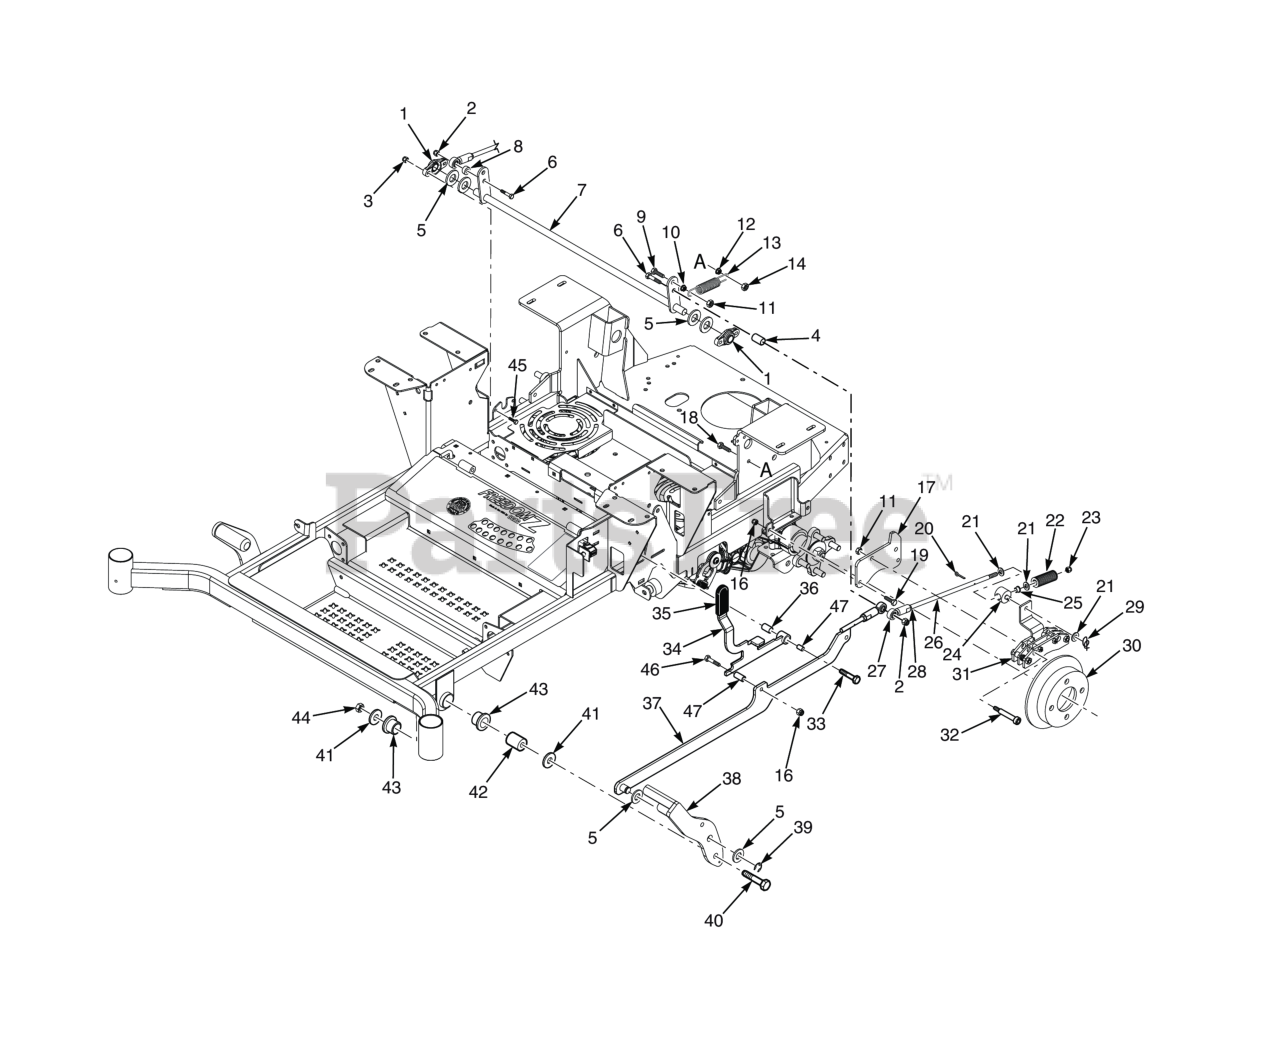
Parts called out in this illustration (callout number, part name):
1	Bearing
2	HEX NUT, ELASTIC STOP LOCK, 3/8-16
3	Nut, Flanged Elastic Stop 1/4-20
4	Spacer, Idler Pulley - SFZ61
5	Flatwasher, 5/8" (.656 x 1.312 x .095")
6	Bolt, Hex Head 3/8-16 x 2-1/4" - 61"
7	Weldment, Brake Lever
8	Spacer, Idler Pulley - SFZ52
9	Bolt, Hex Head, 3/8-16 x 1-1/2"
10	NUT, 3/8-16 SERRATED FLANGE HEX HEAD
11	Bolt, Hex Head 3/8-16 x 1" Ser. Flg.
12	Nut, Serrated Flange 5/16-18 (Right Front Engine Mounting, Briggs and Kohler Only)
13	Spring, Deck Lift
14	Nut, Center Lock, 5/16-18(32)
15	Flatwasher, 3/8" Special (.391 x .938 x .105)
16	HEX NUT, ELASTIC STOP LOCK, 5/16-18
17	Mounting Bracket, Brake
18	Bolt, Heax Head 5/16-18 x 1" (48V / 52V)
19	Bolt, Heax Head 5/16-18 x 1" (48V / 52V)
20	Pin, Cotter 3/32 x .75"
21	Flatwasher, 3/8 (.406 x .812 x .065)
22	Spring, Brake
23	Nut, Elastic Stop 3/8-16, grade 8 black
24	Swivel Assembly, Brake
25	Bearing
26	Link, Brake
27	Rod End, 3/8-24 RH Female
28	Nut, 3/8-24 UNF R.H. Thread
29	Pin, Rue Cotter 3/8" Diameter
30	Spacer, Axle
31	Brake Caliper
32	Bolt, Shoulder 1/2 x 2-1/2"
33	Bolt, Shoulder 1/2 x 2"
34	Latch Assembly, Brake
35	Grip, Brake Handle
36	Bearing
37	Linkage Weldment Assembly, Brake
38	Brake Pedal Weldment
39	RETAINING RING, 5/8" EXTERNAL "E"
40	Bolt, Hex Head 1/2-13 x 3"
41	Flat Washer, 1/2 (.562 x 1.375 x .109)
42	Spacer, Deck Lift Pivot
43	Bearing, Plastic
44	Locknut, Hex 1/2-13 Center Lock
45	CAP SCREW, 1/4-20 X 1" SERRATED FLANGE HEX
46	Bolt, Hex Head 5/16-18 x 1-1/2" - Front
47	Sleeve, Handle Pivot
